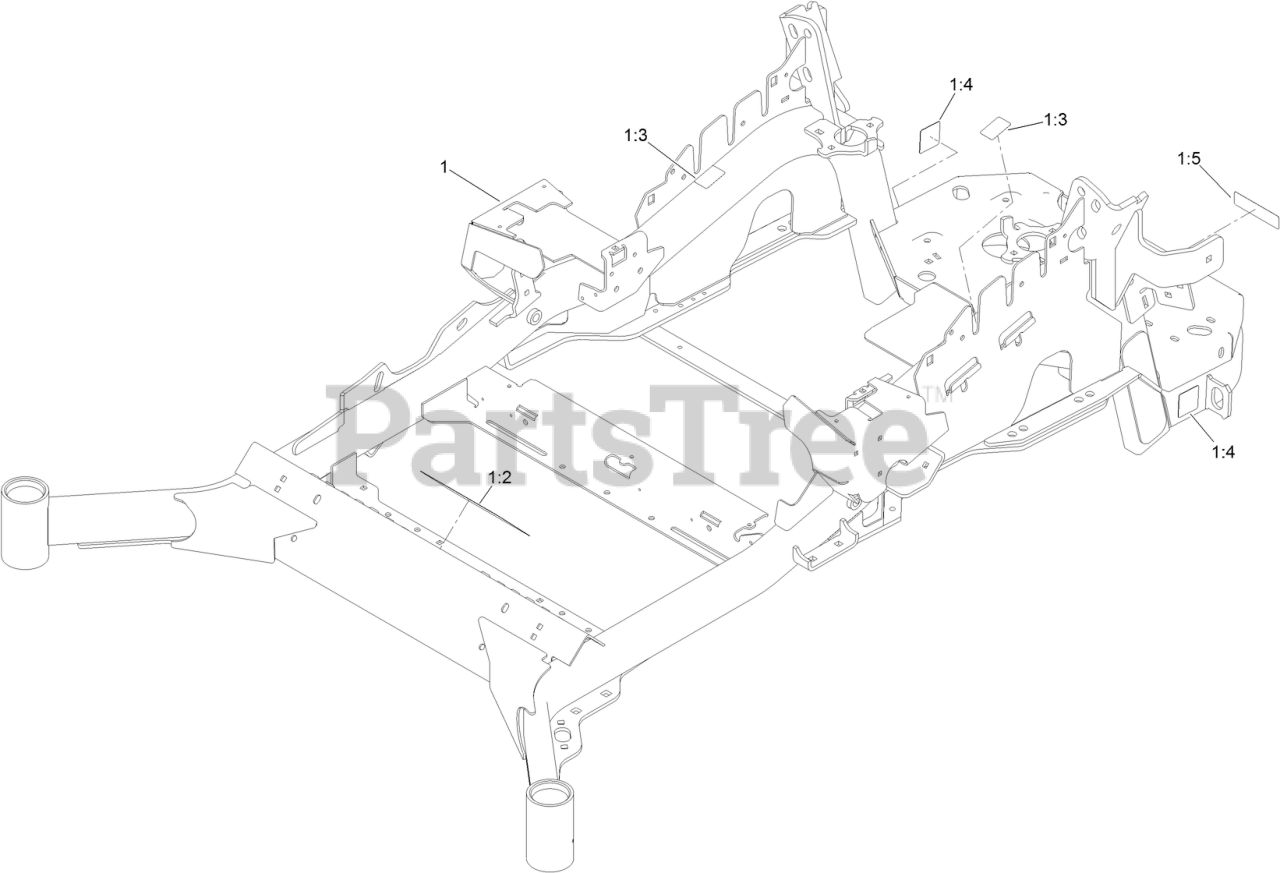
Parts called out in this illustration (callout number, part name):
1	MAINFRAME ASM
1:2	DECAL-DANGER
1:3	DECAL-WARNING
1:4	DECAL-HAZARD, PINCHED FINGER
1:5	DECAL-ARRESTOR, SPARK
